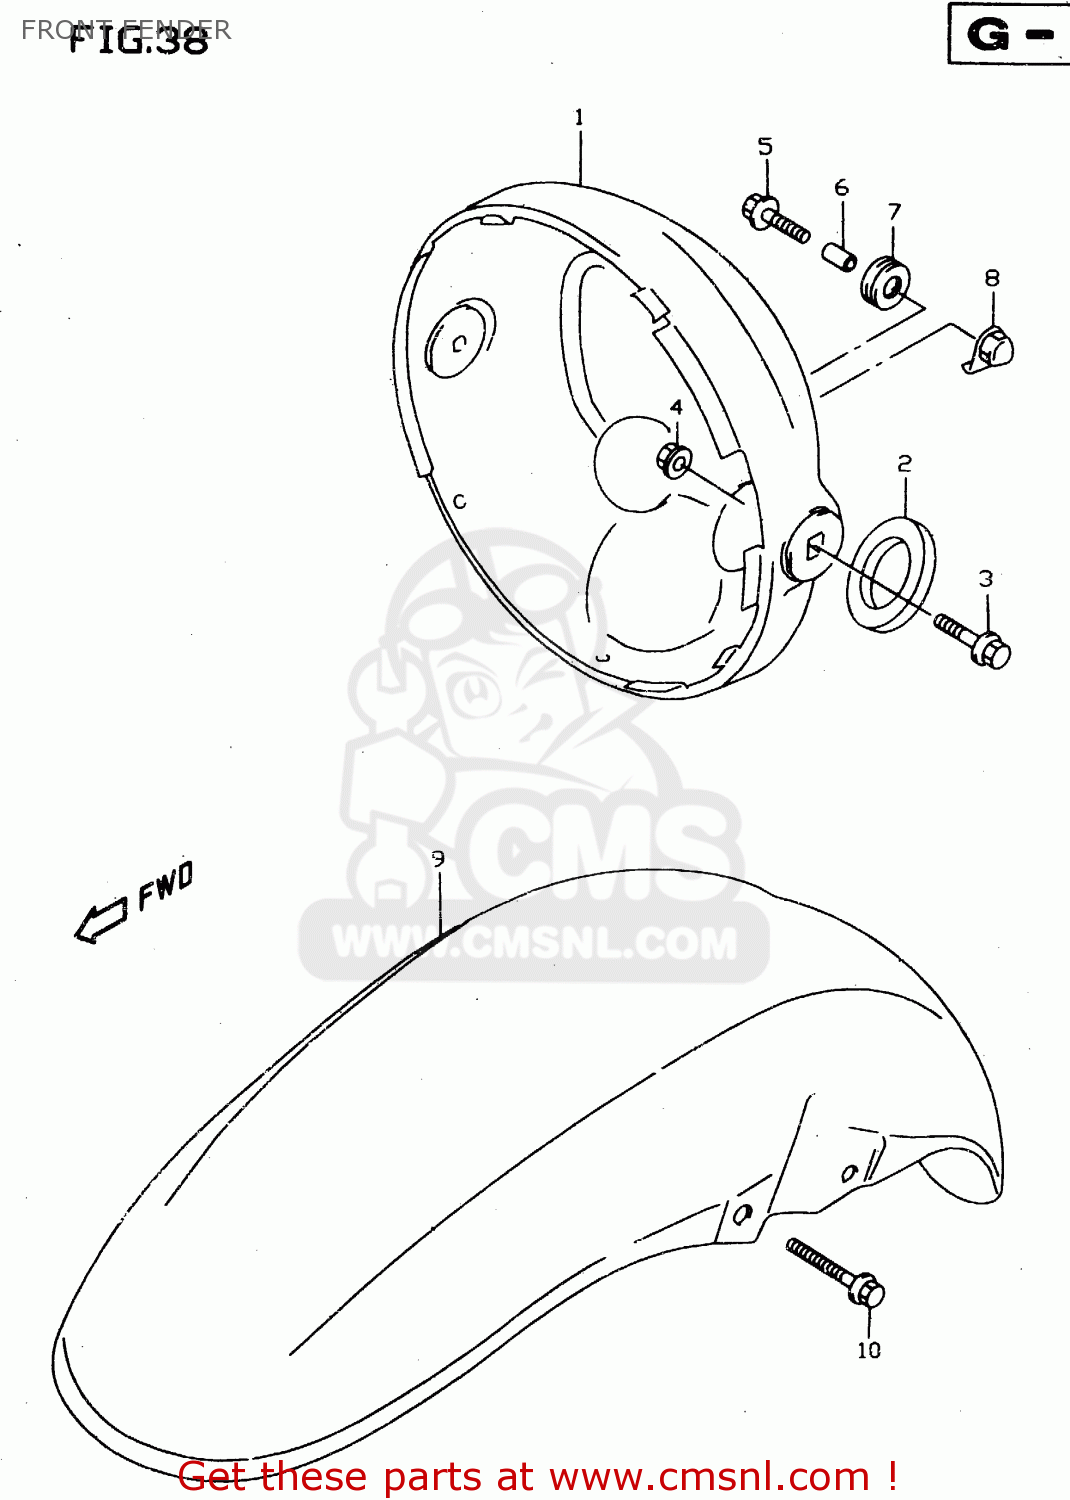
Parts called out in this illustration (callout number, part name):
1	HOUSING,HEADLAMP
2	GROMMET
3	BOLT
4	NUT
5	BOLT
6	SPACER(6.5X10.5X12)
7	CUSHION
8	PLATE,HEADLAMP
9	FENDER,FR
10	BOLT
